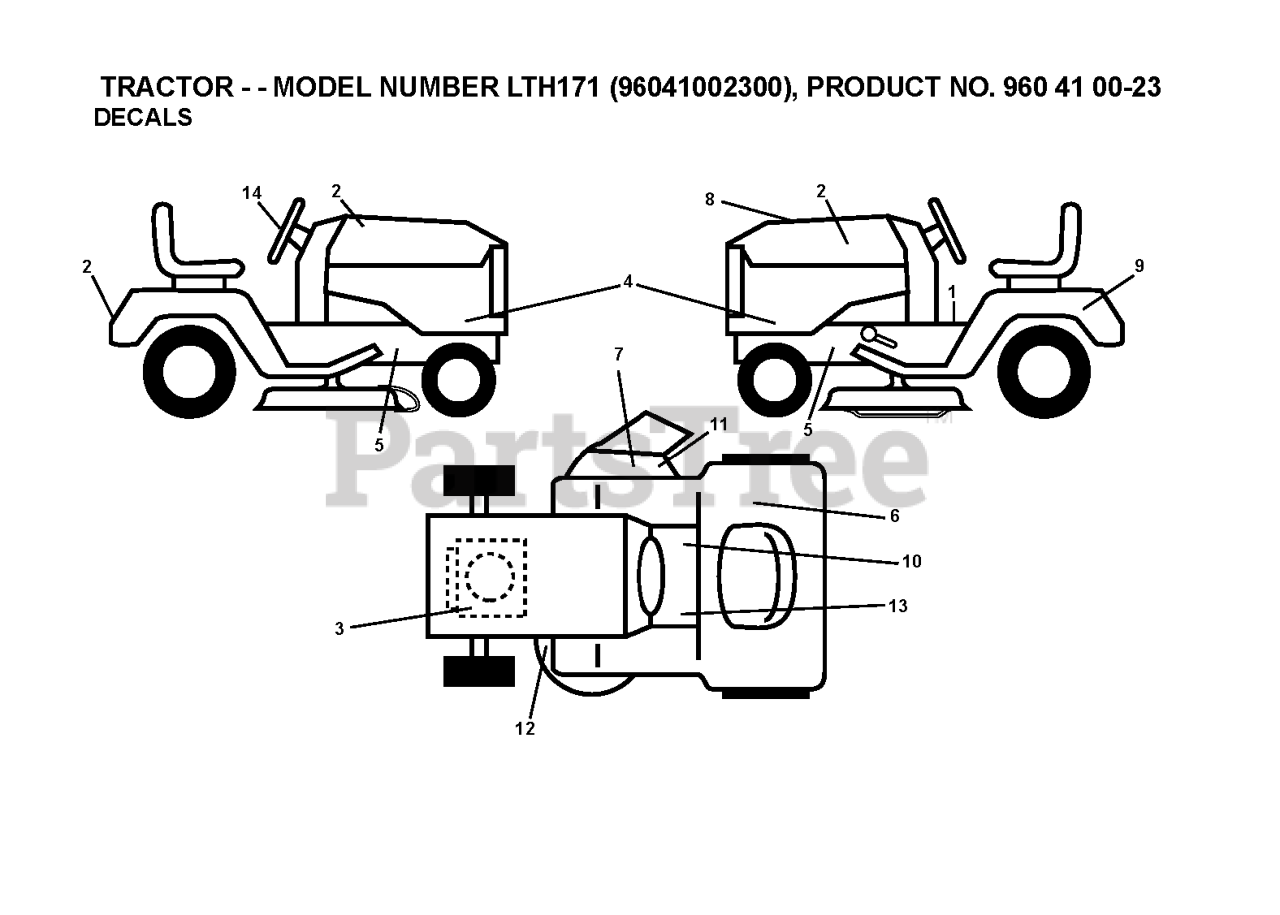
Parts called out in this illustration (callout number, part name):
1	LABEL
2	DECAL.HOOD.NAMELOGO.HUSQ
3	DECAL
6	Decal, Fender 100 DB/CE
11	DECAL, DEFLECT WARNING
12	DECAL V BELT SCHEMATIC
13	DECAL
14	DECAL.WHEEL.STRG.LGN.H
